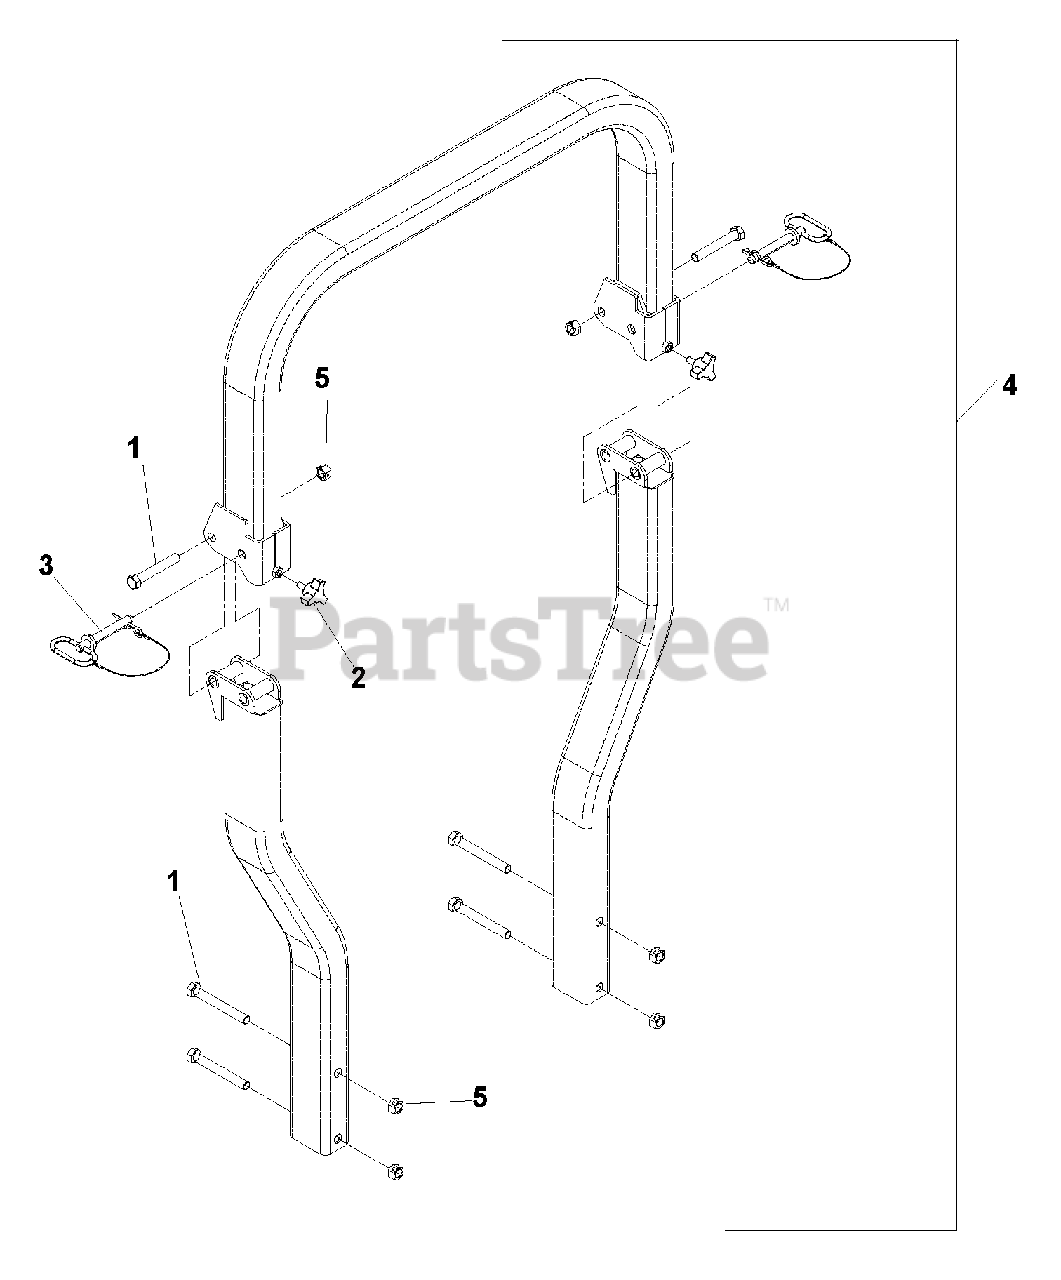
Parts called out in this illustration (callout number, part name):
1	HCS, 1/2C X 3 1/4, GR5
2	KNOB W STUD
3	LANYARD W/PIN, 1/2"
4	ROPS, COMPLETE W/SEAT BELT
5	NUT, 1/2-13, CENTERLOCK
